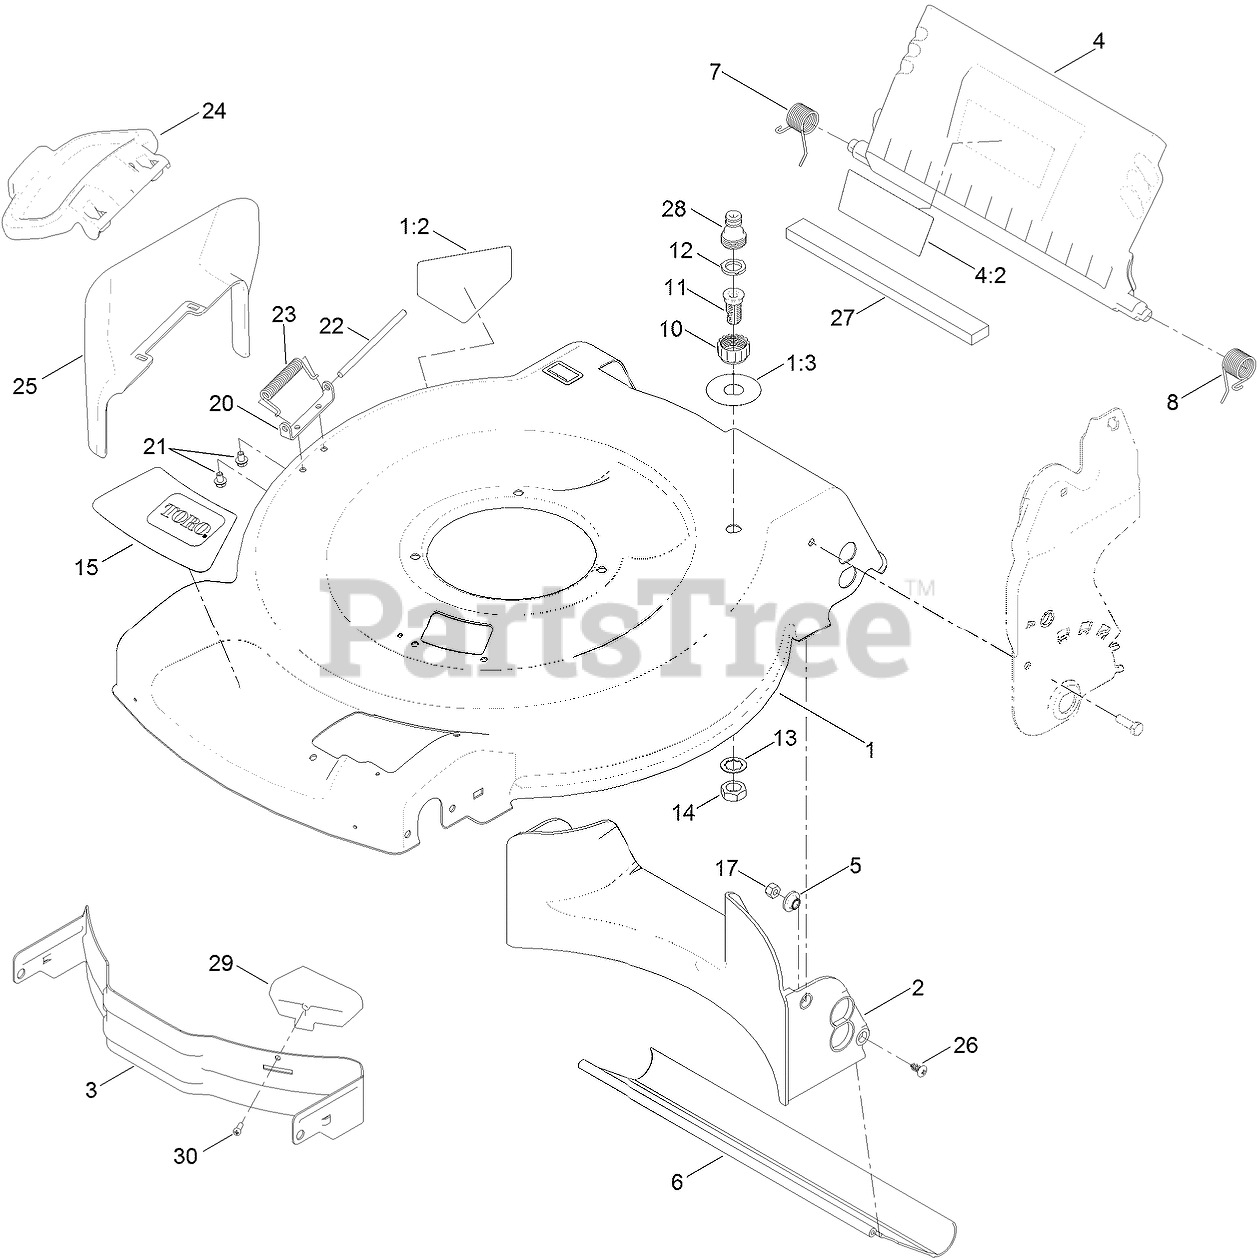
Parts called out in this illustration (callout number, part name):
1	HOUSING ASM
1:2	DECAL-DANGER
1:3	DECAL-PORT, WASHOUT
2	BAFFLE-REAR
3	BAFFLE-FRONT
4	REAR DEFLECTOR ASM
4:2	DECAL-WARNING
5	WASHER-STEPPED, BAFFLE
6	SHIELD-TRAILING
7	SPRING-TORSION
8	SPRING-TORSION
10	COUPLING-HOSE, WASHOUT PORT
11	PORT-WASHOUT
12	WASHER-SEAL, WASHOUT PORT
13	WASHER-LOCK
14	NUT-JAM
15	DECAL-DECK
17	NUT-LOCK, NI
20	BRACKET-COVER
21	SCREW-HWH
23	SPRING-TORSION
24	DEFLECTOR-SIDE
25	CHUTE-DISCHARGE, SIDE
26	SCREW-PTH
27	FOAM-SEAL
28	ADAPTER-CONNECT, QUICK
29	KICKER-FRONT
30	SCREW-PPH
